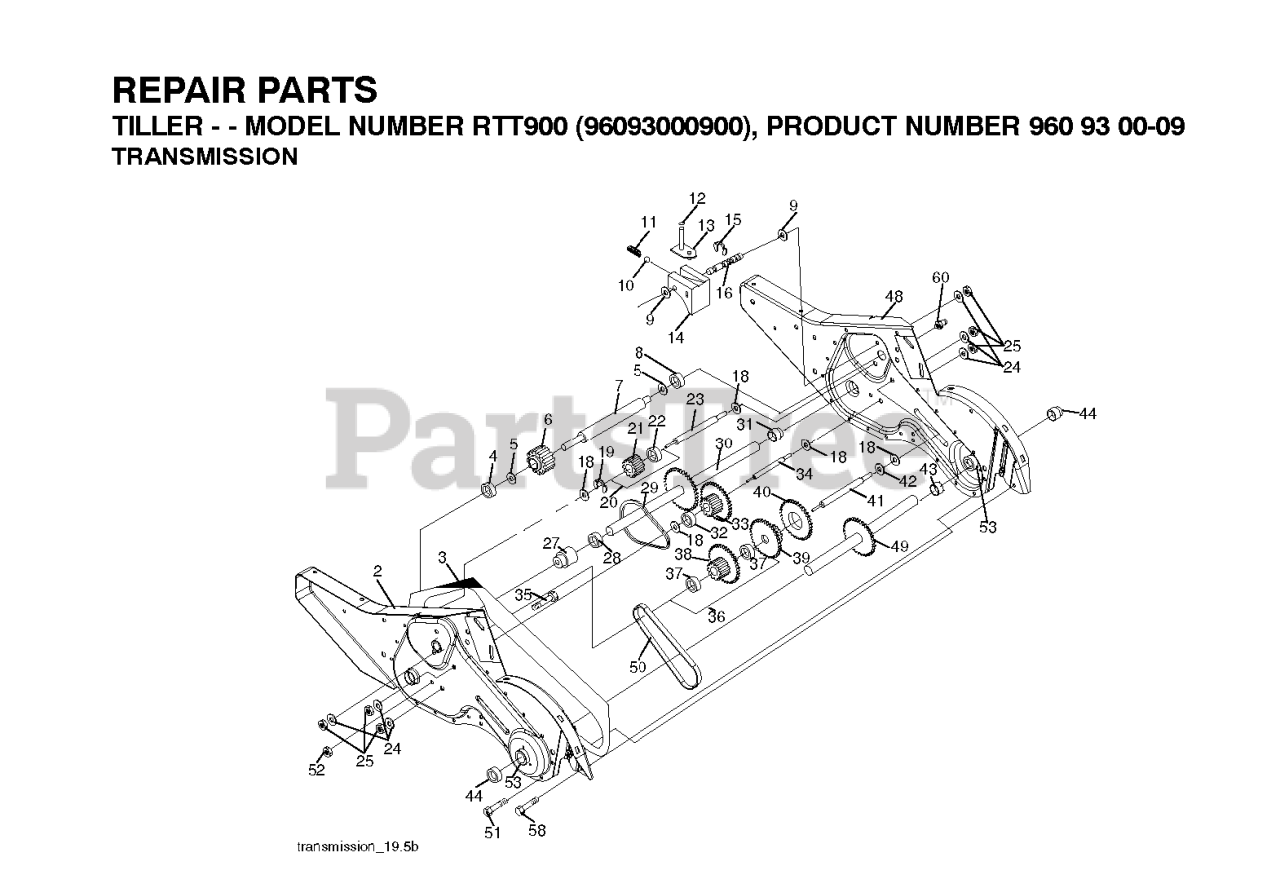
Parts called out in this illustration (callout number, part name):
1	TRANSMISSION ASM.
2	GEARCASE.ASM.CRT.LH.W/BEARING
3	GASKET
4	NEEDLE BRNG LT
5	THRUST WASHER
6	GEAR.PINION.INPUT
7	SHAFT.INPUT."D".TILLER
8	BEARING TI
9	WASHER, SEAL (2 2)
10	STEEL BALL KIT
11	SPRING-SHIFT CRT
13	BRACKET ASM.SHIFT.CRT
14	SHIFT FORK TI
16	SHAFT.SHIFTER.TILLER
20	GEAR ASSY CRT
21	GEAR-REV IDLR CRT
22	NEEDLE BEARING TI
24	LOCKWASHER
25	NUT.ASF.HEX.7/16
27	BEARING, SHAFT LH CRT
30	GROUND SHAFT ASS'Y
31	BEARING, SHAFT RH CRT
33	SPRCKT 8 GEAR CRT
34	SHAFT.SECONDARY.REDUCTION.CRT
35	SCRW WHIZ LOK CRT
36	SPROCKET.ASM.W/BEARING.TILLER
37	BEARING
38	SPROCKET, TINE
41	SHAFT.REDUCTION.TILLER
42	BRNG RACE T
44	SEAL ASM, OIL
48	GEARCASE.ASM.CRT.RH.W/BEARING
49	TINE SHAFT
50	CHAIN.TILLER
51	SCREW
52	NUT
53	KIT.BEARING.TILLER.
58	BOLT SHOULDER 1/4-20 UNC X.875
60	FITTING.GREASE.TAPERED
